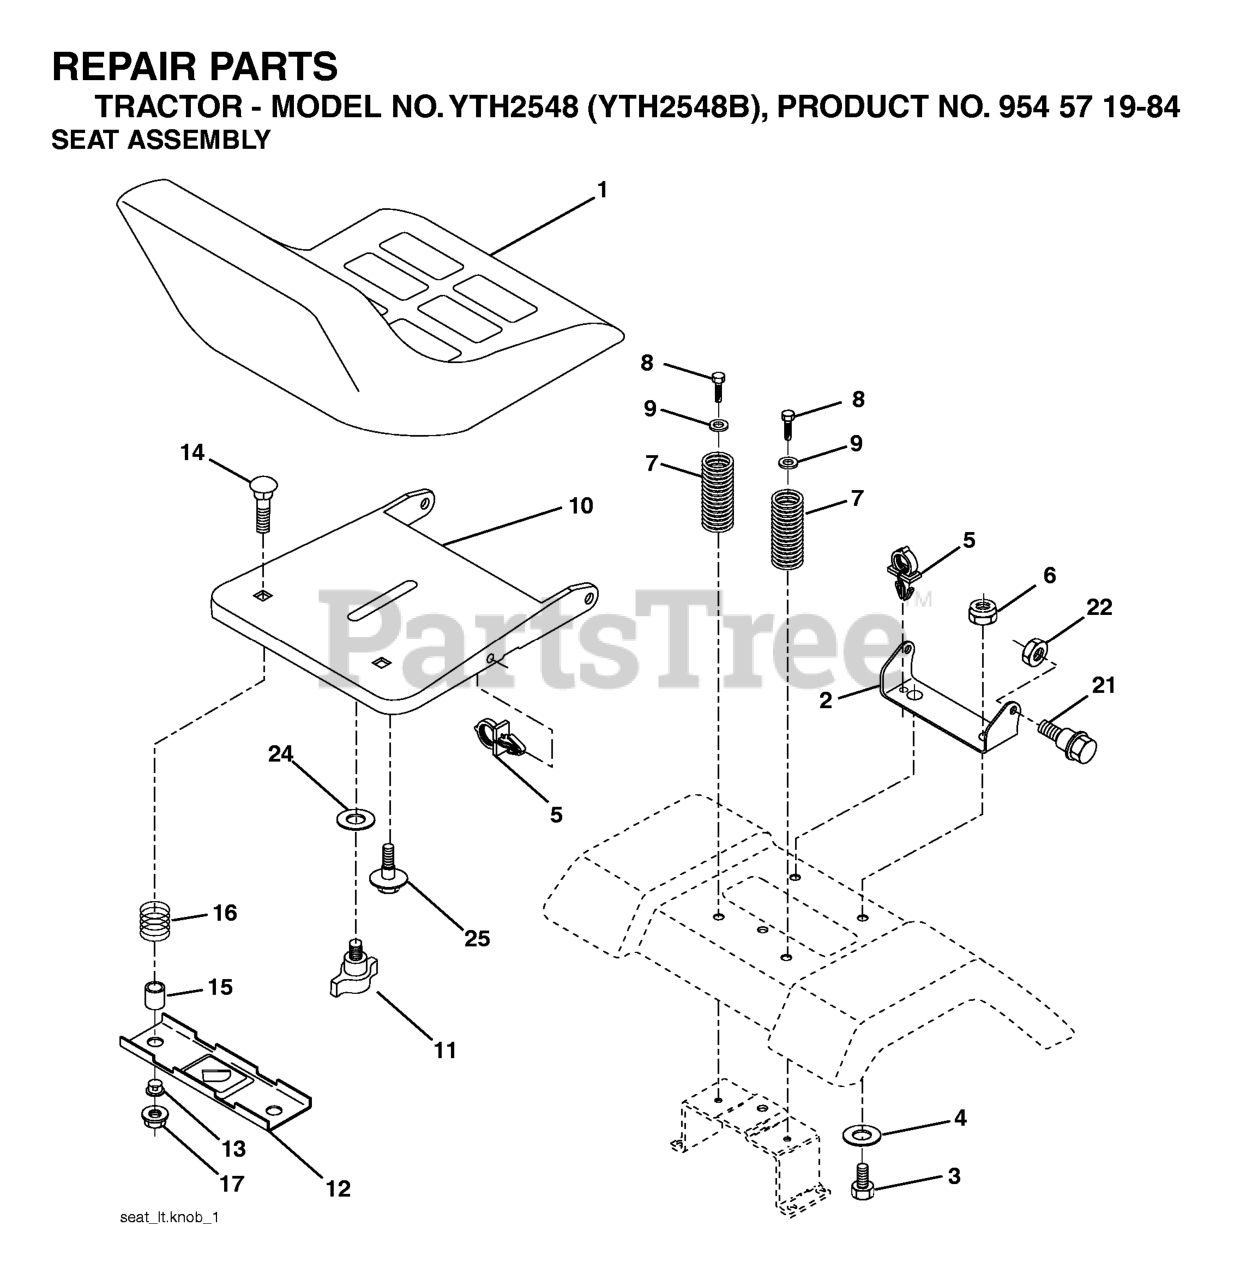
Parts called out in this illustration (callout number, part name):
1	SEAT.XH150.GRY
2	SEAT PIVOT BRKT
3	BOLT, HEX 3/8-16X1
6	NUT
7	SPRING COMPRESSION
8	SCREW 3/8-16X1
9	WASHER
10	PAN SEAT
11	KNOB.SEAT.ADJ.WINGNUT
12	BRKT SWITCH
14	BOLT.ROUND.HEAD.SQUARE.NECK
15	SPACER SPLIT
16	SPRING COMPRESSED
17	NUT T
21	BOLT.SHOULDER.5/16-18
22	NUT.71038.31-18.HEX.NYLOCK
25	BOLT,SHOULD
